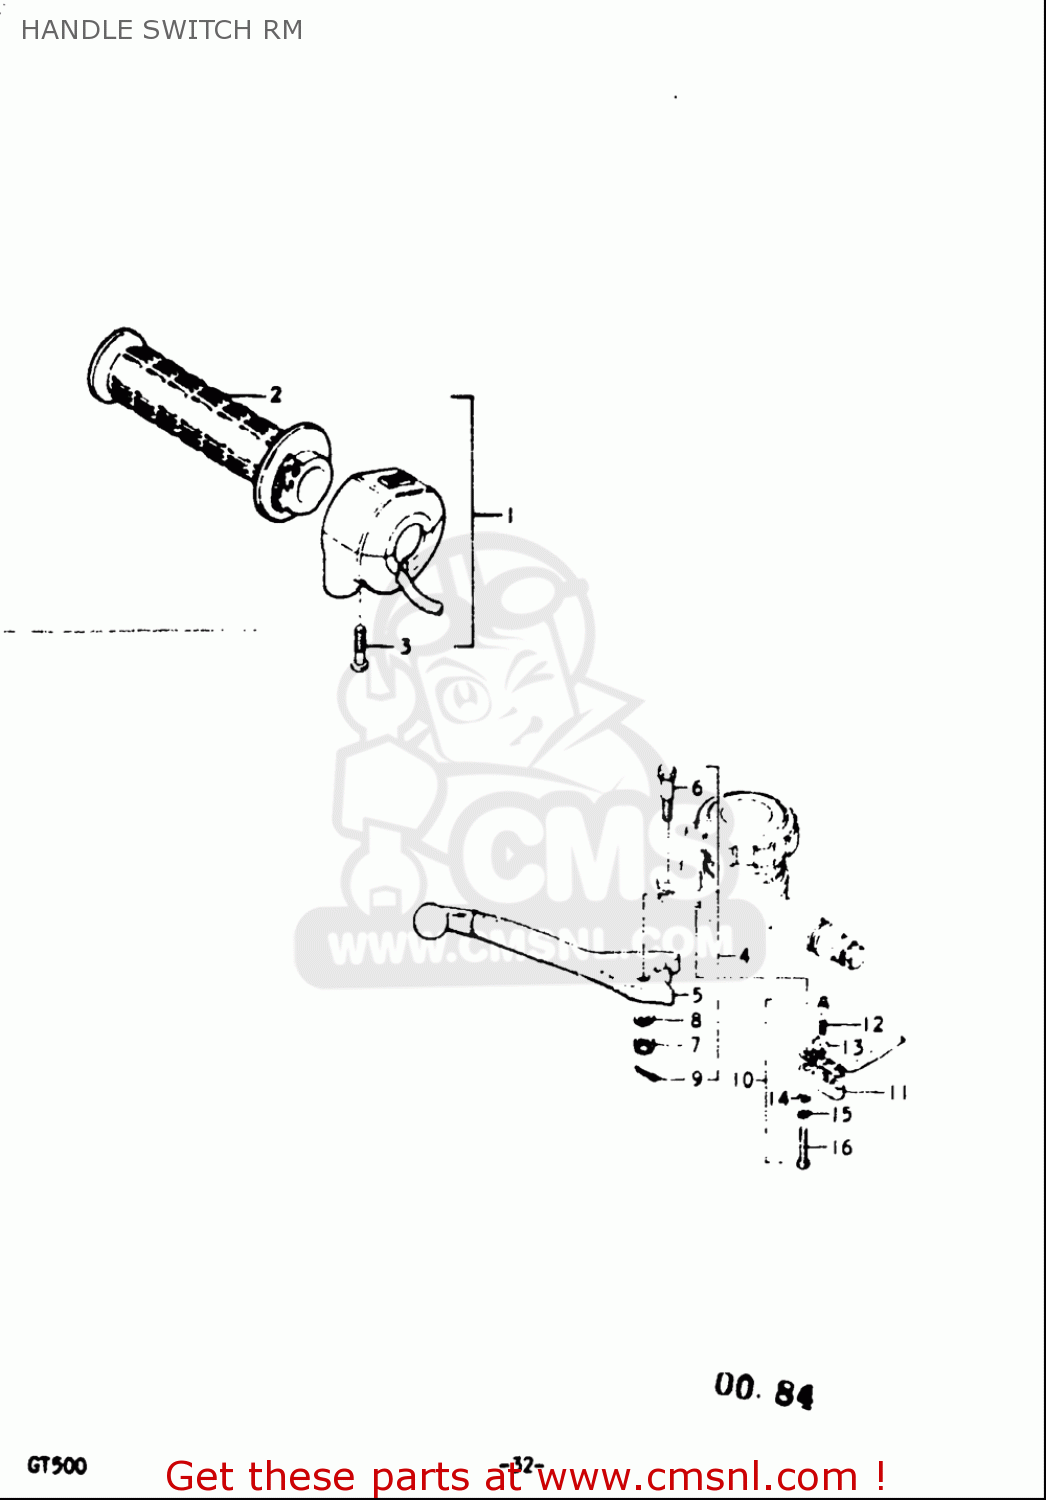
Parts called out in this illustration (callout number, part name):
2	GRIP,THROTTLE
3	SCREW
5	LEVER,BRAKE
6	BOLT
7	NUT,LEVER FITTNG
8	WASHER,LOCK
9	PIN 16X20
10	SWITCH ASSY,STOP
11	COVER,FR BK TERMINAL BASE
12	CONTACT,SWITCH
13	CONTACT,SWITCH
14	WASHER
15	WASHER,LOCK
16	SCREW
